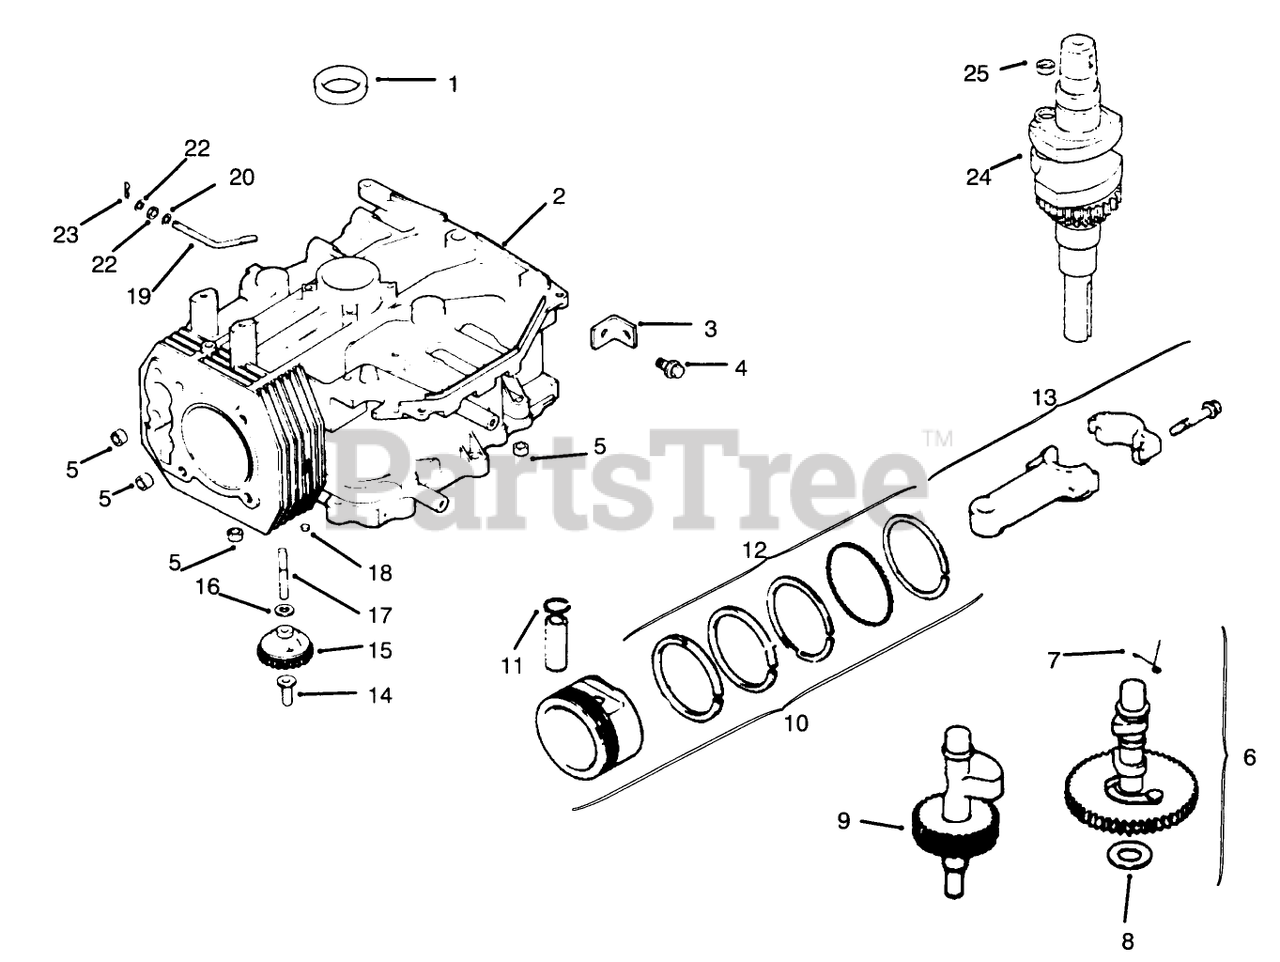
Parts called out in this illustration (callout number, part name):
1	Seal-Crankshaft
2	Shortblock
3	Strap-Lifting
4	Screw
5	Pin-Dowel
6	Camshaft Assembly
7	Spring-Actuating
8	Shim-Camshaft
9	Shaft Balance
10	Set Piston w/Ring STD
11	Retainer-Piston Pin
12	Ring Set STD
13	Rod Connecting STD
14	Pin-Governor
15	Gear, governor
16	Washer
17	Shaft-Gear, Governor
18	Plug
19	Shaft-Governor Cross
20	Washer
21	Seal-Cross Shaft
23	Pin-Hitch
24	Crankshaft ASM
25	Plug-Cup
